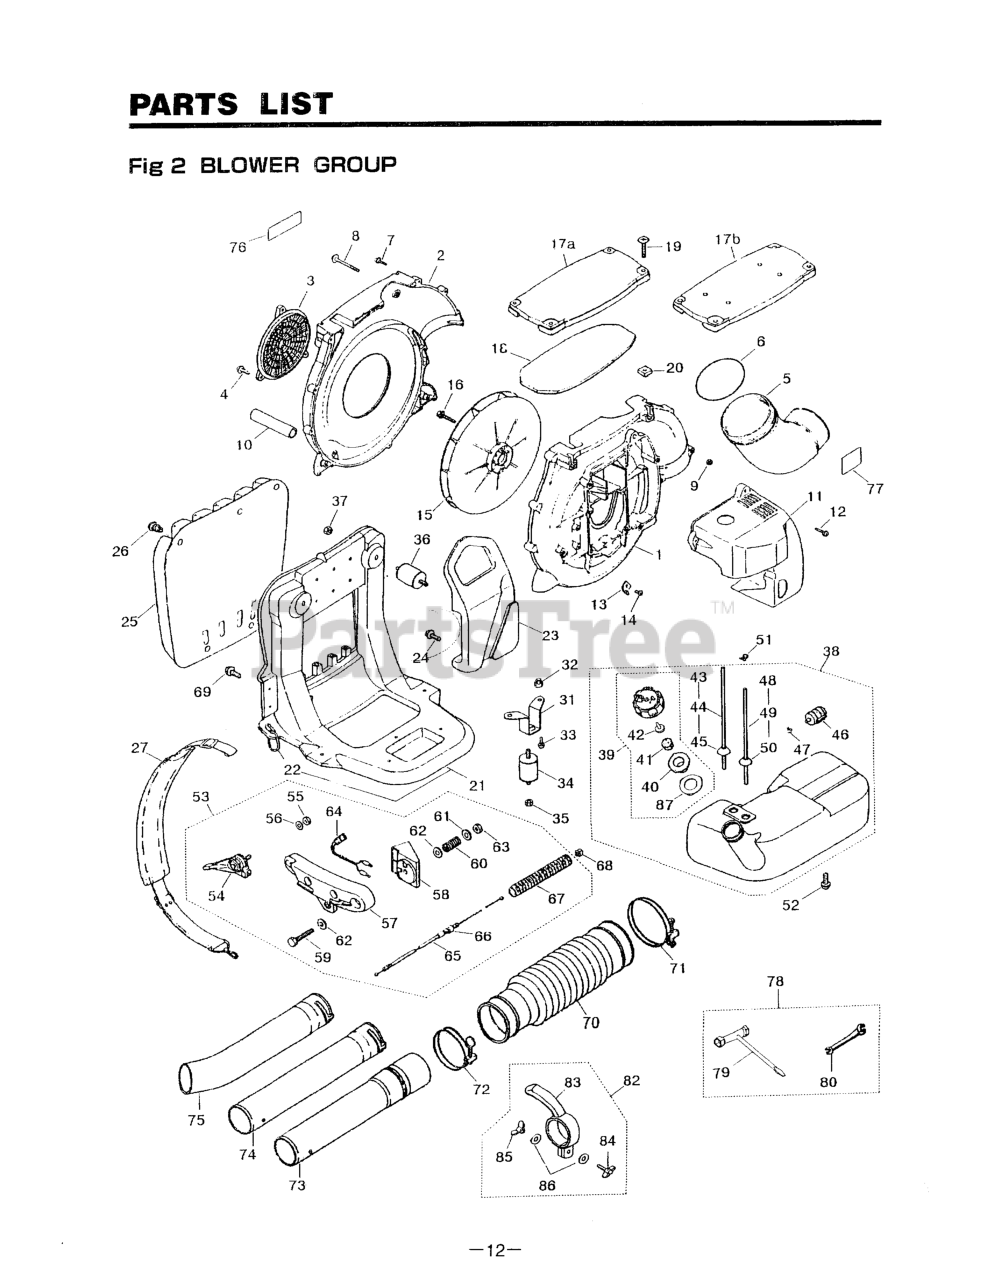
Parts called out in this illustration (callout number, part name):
1	CASE, VOLUTE
2	COVER, VOLUTE
3	NET, GUARD (RPLS-12222)
6	O-RING
7	SCREW
9	NUT (B)
11	COVER, ENGINE (RPLS-11210)
12	SCREW
15	FAN (REPLACES 3490-12110)
16	BOLT (RPLS 3405-12211)
17A	COVER (RPLS -13111)
18	COVER, PACKING
19	SCREW
20	NUT
22	RING (USE -21121)
23	HANGER (RPLS -21210)
25	PAD (RPLS -21310)
26	CLIP (RPLS 3490-21320)
31	BRACKET (RPLS -22510)
32	WASHER
33	SCREW, M5X20 (RPLS.1400-75510)
34	MOUNT (A) (RPLS 3490-22110)
35	NUT, M6 X 5
36	MOUNT (B) (RPLS 3405-22120)
37	NUT, M6 X 5
38	TANK ASSY (RPLS -23005)
39	CAP ASSY (RPLS -23202)
43	PIPE (RPLS 3490-23410)
44	PIPE (USE 1696-85400)
45	GROMMET
46	FILTER ASSY
47	CLIP (REPLACES 2841-31280)
48	PIPE ASSEMBLY
49	PIPE (USE 1620-81710)
50	GROMMET
51	CLIP
52	SCREW, M5 x 12
53	LEVER (EB441)
54	LEVER, THROTTLE
55	NUT (B)
56	WASHER, M5x.8(RPLS 01624-20508
58	BRACKET
59	BOLT
60	SPRING
61	WASHER
62	WASHER, FLAT
63	NUT, M6 X 5
64	SWITCH, STOP
65	CABLE COMP,THROTTLE EB441
67	TUBE (USE 5548-73310)
68	NUT, M6 X 5
69	BOLT
70	HOSE, FLEXIBLE
71	2756-51510 (RPLS. 07280-09832)
73	JOINT, SWIVEL
74	PIPE, EXTENSION
75	PIPE, BENT
78	TOOL SET
80	SPANNER, 8 X 10 (RPLS 2540- )
82	BLOWER ASSIST HANDLE
83	EBH100
84	BOLT, WING
85	NUT, WING
86	WASHER
87	PACKING (RPLS -85321)
